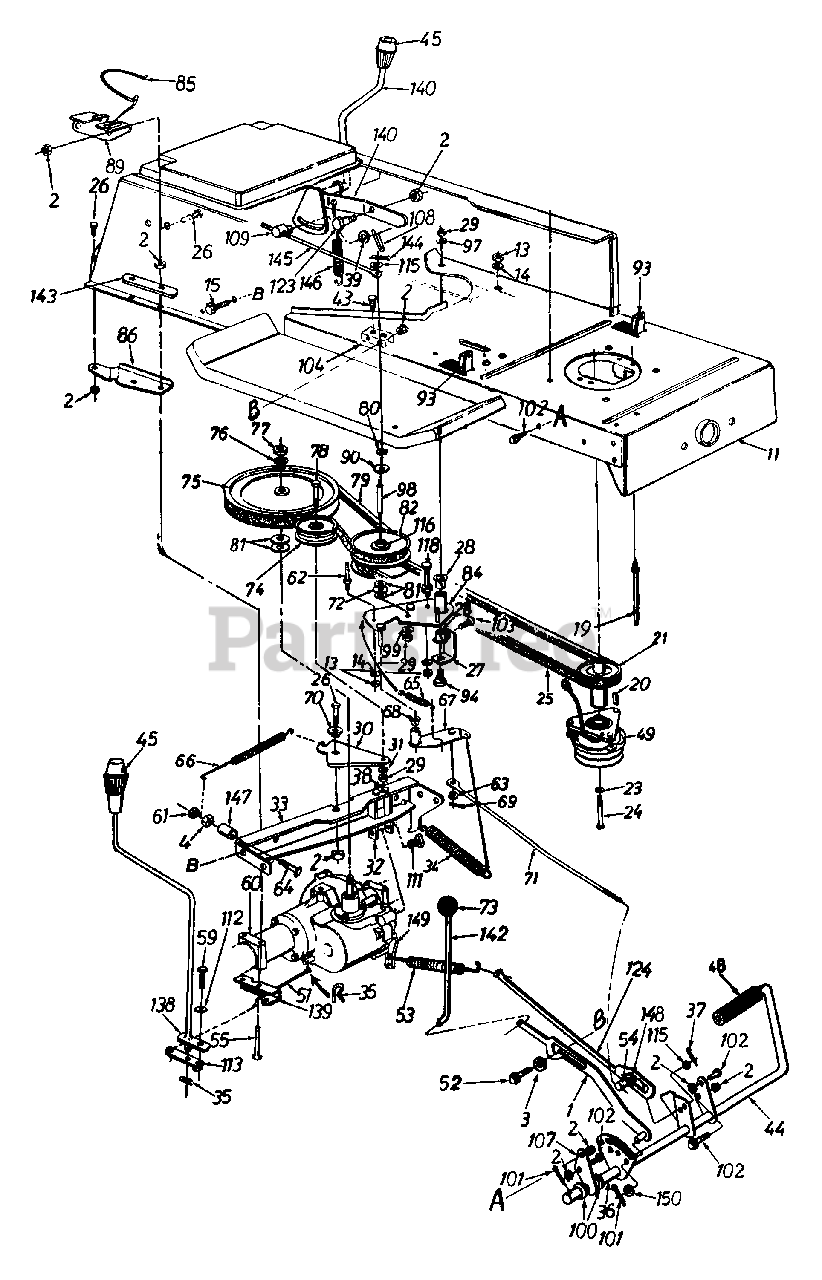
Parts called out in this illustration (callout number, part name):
1	Parking Brake Lockout Brkt. Ass'y.
2	Hex Sems Nut 5/16-18 Thd.
3	Fl-Wash. .442" I.D. x 1.38" O.D.
4	Hex Nut 5/16-24 Thd.
14	L-Wash. 1/4" I.D.
19	Belt Guard Pin
20	Sq. Key 1/4" x 1/4" x 1.5"
21	Engine Pulley
23	L-Wash. 7/16" I.D.
24	Hex Bolt 7/16-20 x 2.5" Lg.
25	Variable Speed Belt
26	Hex Bolt 5/16-18 x .75" Lg.
27	Bearing Shaft Bracket Ass'y.
28	Flanged Nyliner Brg. .63" I.D. x .6" Lg.
29	Hex Nut 3/8-24 Thd.
30	Idler Bracket
31	L-Wash. 3/8" I.D.
35	Inter. Cotter Pin
36	Spacer .63" I.D.
37	Cotter Pin 1/8" Dia. x 1.0" Lg.
38	Self-Tap Scr. 5/16-18 x .5" Lg.
39	FL-Wash. .51" I.D. x .75"
43	Hex Wash. Hd. S-Tap Scr. 1/4-20 x .50" Lg.
48	Foot Pad
49	Electric Clutch
51	Shift Lever Rod
52	Shld. Bolt .437"
53	Ext. Spring 3.6"
54	Ferrule
55	Hex Bolt 5/16-18 x 3.25"
59	Hex Bolt 1/4-28 x .62" Lg.
60	Transaxle Complete
61	Hex L-Nut 1/4-20 Thd.
62	Belt Guard Pin 1/4-20 Thd.
63	Fl-Wash. .34" I.D. x .68" O.D.
64	Hex Wash. TT-Tap Scr. 1/4-20 x 1.75"
65	Ext. Spring 2.59" Lg.
66	Ext. Spring .5" O.D. x 4.35"
68	Flanged Bearing
69	Cotter Pin 3/32" Dia.
70	Shoulder Spacer .27" Lg.
71	Speed Control Link
72	Truss Bearing .56 Dia. x 1.25"
74	Fl-Idler Pulley 3.25" x .75"
76	L-Wash. 1/2" I.D.
77	Hex Jam Nut 1/2-20 Thd.
78	Hex Bolt 3/8-24 x 1.75" Lg.
79	Variable Speed Belt
80	Snap Ring .56" Dia.
81	Fl-Wash. .56" I.D. x 1.0" O.D.
82	Variable Speed Pulley Ass'y. 5" O.D.
90	Teflon Washer .565" I.D.
93	Safety Switch (Clutch)
94	Shld. Bolt 3/8-24 x 3.12" Lg.
97	Bell-Wash. .38" I.D. x .88"
99	Bell-Wash. .39" I.D. x 1.12"
100	Fl-Wash. .64" I.D. x .94"
101	Cotter Pin 3/32" Dia. x 1" Lg.
102	Hex Wash. Hd. Scr. 5/16-18 x .62" Lg.
103	Hex Wash. Hd. AB-Tap Scr. .75" Lg.
107	Pedal Bracket
109	Ferrule
111	Hex Wash. Tap Scr.
112	Bell-Wash. .265" I.D. x .75"
113	Shift Lever Link Ass'y.
115	Fl-Wash. .385" I.D. x .62"
116	Needle Brgs.
118	Hex Bolt 1/4-20 x 3.5" Lg.
123	Shld. Bolt .437" Dia. x .162"
124	Brake Rod Ass'y.
138	Shift Lever Ass'y.
139	Shift Lever Support Brkt.
140	Speed Selector Lever Ass'y.
142	Brake Lockout Rod
144	Cotter Pin 1/8" x 3/4" Lg.
145	Speed Selector Rod
146	Ext. Spring 3.97" Lg.
147	Spacer .326" I.D. x .47"
148	Fl-Wash. 5/8" I.D. x 1.25"
149	Actuating Arm
150	Fl-Wash. .385" I.D. x .62" O.D.
